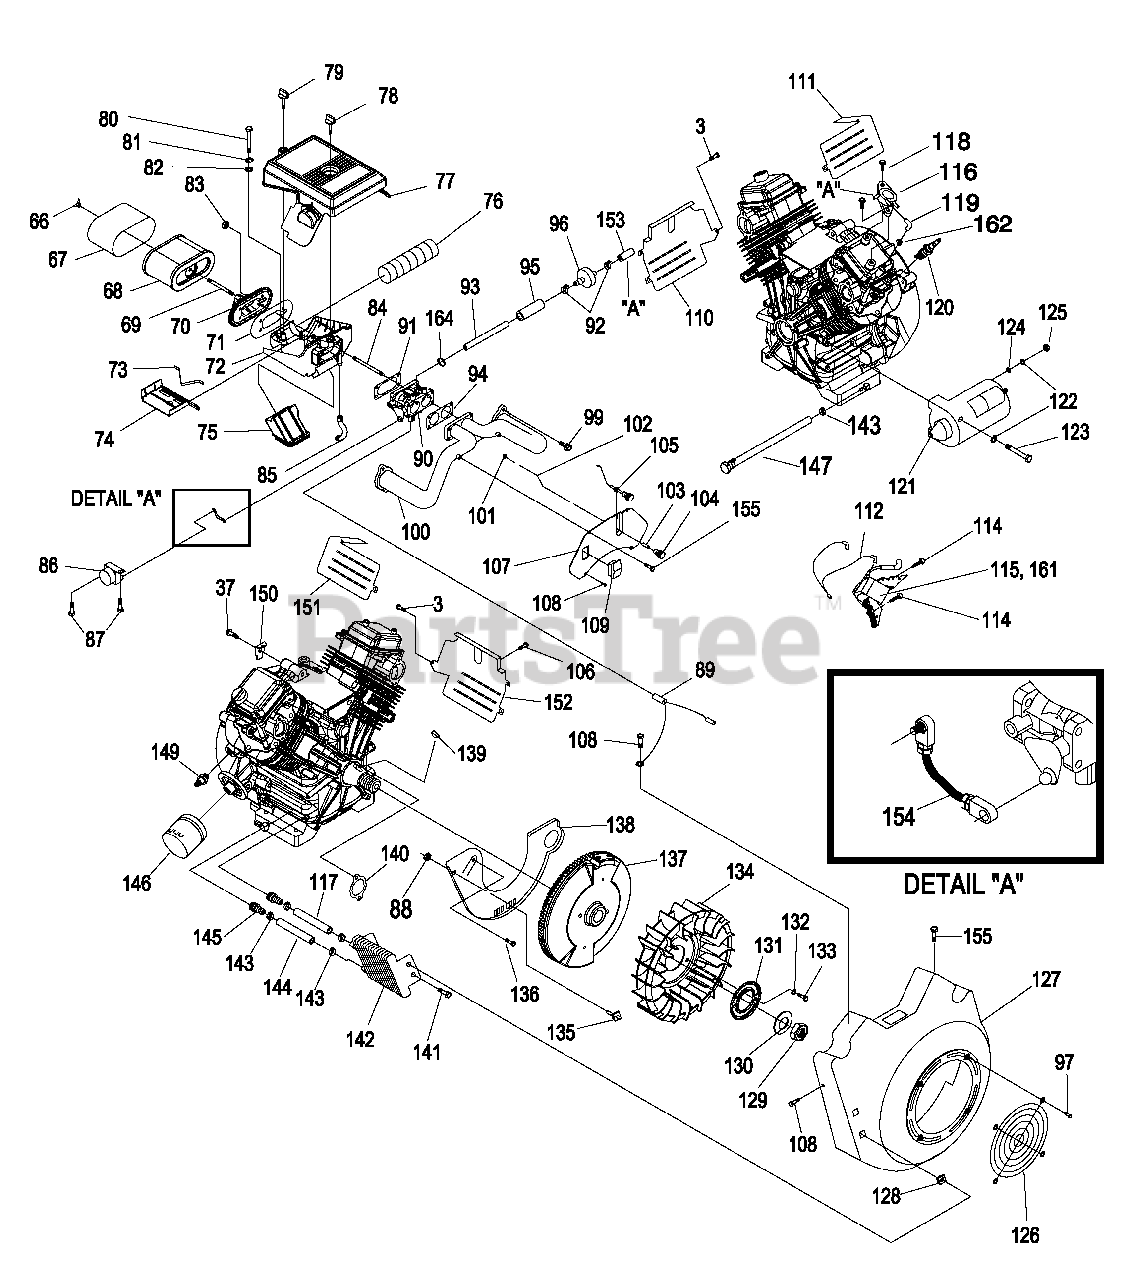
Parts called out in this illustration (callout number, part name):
66	WINGNUT, AIRBOX
67	PRECLEANER, AIR
68	ELEMENT, AIR CLEANER
69	STUD M6-1.0 X 73
70	ADAPTOR, SPIT BACK
71	GASKET, SPITBACK
72	BASE, AIRBOX
73	SPRING, WINTER/SUMMER VALVE
74	VALVE, SUMMER / WINTER
75	SNORKEL, AIR INTAKE
76	TUBE, HEAT RISER 50.8 I.D.
77	COVER, AIRBOX
78	KNOB, AIRBOX 17mm
79	KNOB, AIRBOX 95MM
80	SCREW HHC M6-1.0 X 35
81	WASHER LOCK M6-1/4
82	WASHER FLAT 1/4
83	NUT, HEX FLANGE WHIZ M6-1.0
84	STUD, METRIC
85	HOSE, BREATHER
86	ASSY,CONTROLLER, GTH990 PORTABLE
87	SCREW HHTT M5-0.8 X 10
88	NUT, HEX LOCK M5-0.8 ZINC
89	ASSEMBLY, WIRE
90	CARBURETOR, H990 W/BALL STUD
91	GASKET, CARB TO SPACER (GT-990)
92	CLAMP HOSE BAND 1/4
93	HOSE 1/4 ID SAE 30R7 GREENBAR 9" PRECUT
94	GASKET, MANIFOLD TO CARBURETOR
95	SLEEVING, FLEXO HW 3/4 3"
96	FILTER, FUEL
97	SCREW, HHTT M6-1 x 10 LONG
98	NUT, HEX LOCK M5-0.8 ZINC
99	SCREW, SHC M8-1.25 x 25 LG SEMS
100	MANIFOLD, INTAKE
101	NUT HEX M3-0.5
102	ROD, SUMMER / WINTER VALVE
103	BUSHING, MINI CONTROL PANEL
104	KNOB, CONTROL SUMMER / WINTER
105	CHOKE ASSEMBLY
106	SCREW TAPTITE M5-0.8 X 8 ZP
107	PANEL, CONTROL FACE PLATE
108	SCREW TAPTITE M6-1.0X 12 CLEAR ZINC
109	SWITCH ROCKER
110	WRAPPER, LOWER CYLINDER 2
111	WRAPPER, UPPER CYLINDER 2
112	ASSEMBLY, GROUND WIRE
114	SCREW TAPTITE M6-1.0 X 20 ZINC
115	ASSY, IGN COIL W/DIODE NO ADV
116	PUMP, IMPULSE
117	HOSE 3/8" 300PSI 6.5" LG OIL
118	SCREW, HHFCS M6-1.0 X 16 G8.8
119	ELBOW, RUBBER 90 DEG. GASOLINE
120	SPARKPLUG, CHAMPION RC14YC
121	STARTER MOTOR GEAR REDUCED
122	WASHER LOCK M8-5/16
123	SCREW HHC M8-1.25 X 85 G8.8
124	WASHER, FLAT M8
125	NUT, HEX M8-1.25 YELLOW ZINC
126	GUARD,FAN
127	HOUSING, BLOWER GAS COOLER
128	NUT, GROMMET 1/4 PLUG
129	NUT,HEX M24
130	WASHER, M24
131	PLATE, FAN
132	WASHER SHAKEPROOF INT M8 SS
133	SCREW HHC M8-1.25 X 12 G8.8
134	FAN, NYLON
135	ASSY,GROUND WIRE CONNECTOR
136	SCREW TAPTITE M6-1X10 YELLOW CHROME
137	FLYWHEEL ASSEMBLY
138	PLATE, BACKING GT990 W/OIL COOL ZINC
139	KEY, WOODRFF 4 X 19D
140	GASKET, MANIFOLD / PORT
141	PLASTITE,1/4-15 X 3/4
142	COOLER, OIL
143	CLAMP, HOSE OETIKER STEPLESS 18.5mm
144	HOSE 3/8" 300PSI 6.5" LG OIL
145	BARBED STR 1/4NPT X 3/8
146	OIL FILTER, 90mm w/LOGO
147	ASSEMBLY, OIL DRAIN HOSE
149	SWITCH, OIL PRESS
150	BRACKET, AIRBOX SUPPORT
151	WRAPPER, UPPER CYLINDER 1
152	WRAPPER, LOWER CYLINDER 1
153	HOSE, 1/4" SAE 30R7 GREENBAR
154	ASSY, ROD, GOV. STEPPER MOTOR
155	SCREW HHHC M6-1.0 X12
157	NUT, LOCK HEX M3-0.5 (GT-990)
160	SCREW HHFC M6-1.0 X 10mm
161	ASSY, IGN COIL W/DIODE NO ADV
162	CLAMP, HOSE BAND GREEN
163	BALL STUD, 10mm
164	CLAMP, HOSE WORM GEAR
